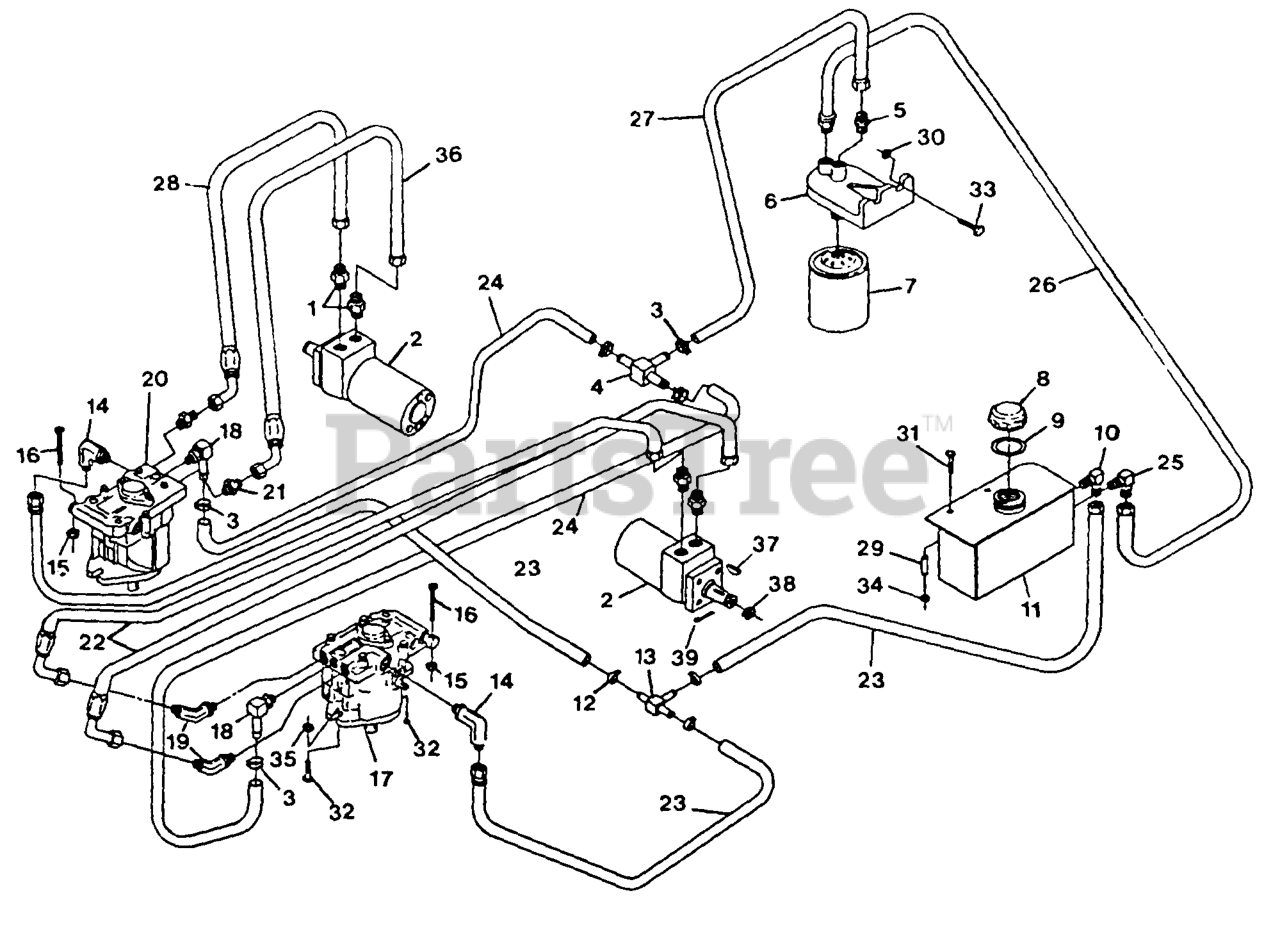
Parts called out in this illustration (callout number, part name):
1	FITTING-STRAIGHT
2	HYD MOTOR ASM
3	CLAMP-HOSE
4	FITTING-TEE, HOSE
5	LINK,HINGE PLTD
9	GASKET-CAP, TANK
10	FITTING-ELBOW
12	CLAMP-HOSE
13	FITTING-TEE, HOSE
14	FITTING-90 DEG
18	FITTING
19	FITTING-HYD, 45 DEG
21	FITTING-STRAIGHT
22	HOSE-PRESSURE, HIGH
23	ASM,HOSE CASE DRAIN
26	ASM,HOSE LO PRESSURE
27	ASM,HOSE CHARGE LINE
37	KEY-WOODRUFF
39	PIN-COTTER
